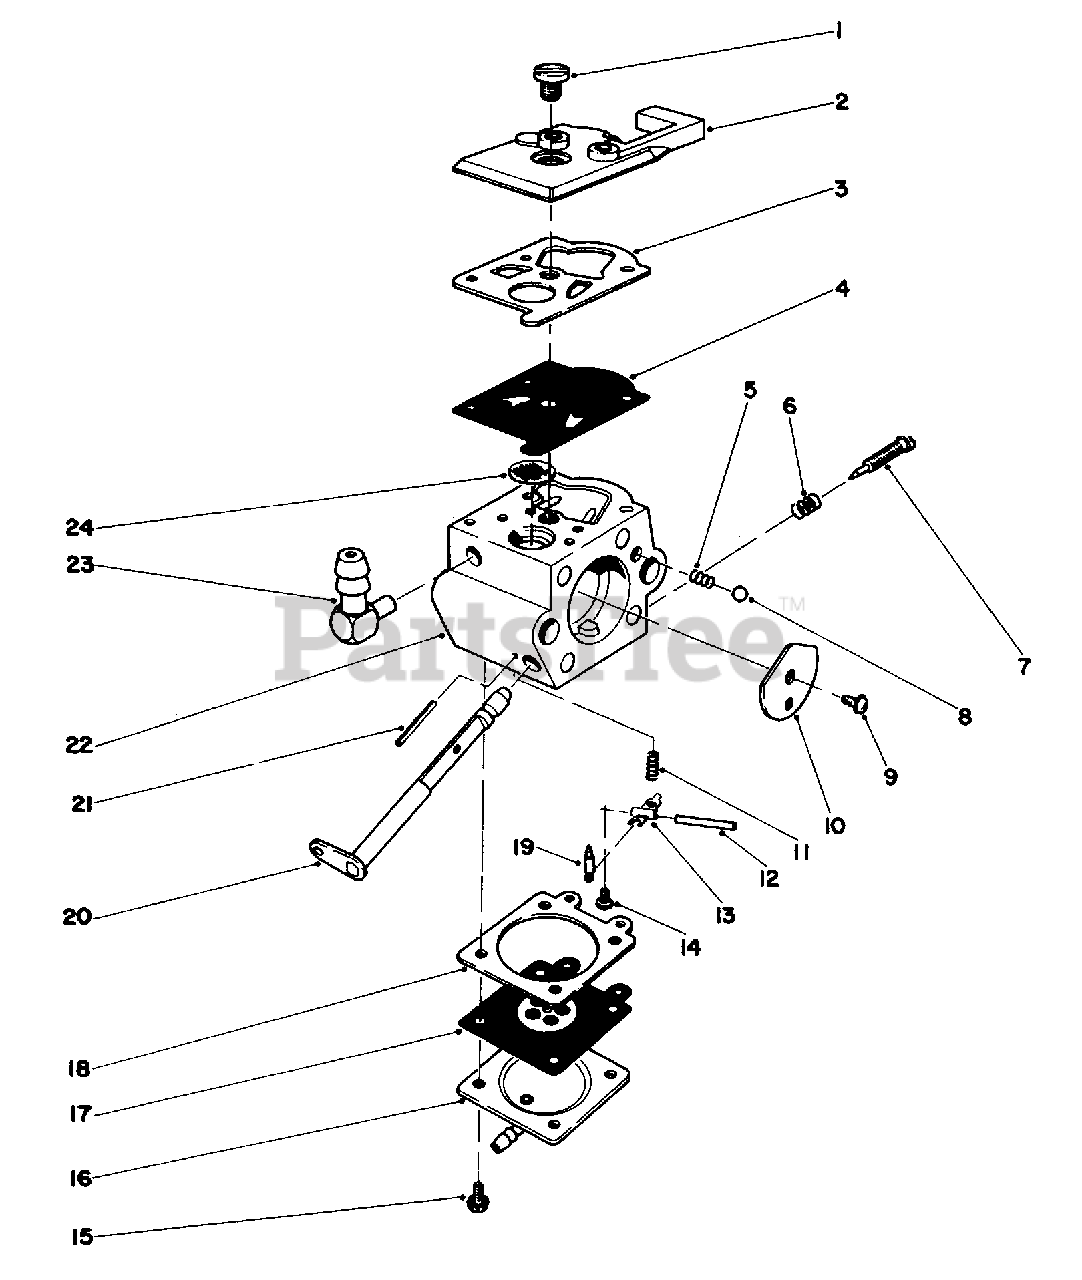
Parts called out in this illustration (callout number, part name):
1	Pump Cover Screw
2	Pump Cover
3	Pump Gasket
4	Pump Diaphragm
5	Choke Friction Spring
6	High Speed Needle Adj. Spring
7	High Speed Needle
8	Choke Friction Ball
9	Valve Screw
10	Choke Valve
11	Metering Lever Spring
12	Metering Lever Pin
13	Metering Lever
14	Metering Lever Pin Screw
15	Metering Diaphragm Screw
16	Metering Diaphragm Cover
17	Metering Diaphragm Assy.
18	Metering Diaphragm Gasket
19	Inlet Needle Valve
20	Choke Shaft Assembly
21	Roll Pin
22	Carburetor Body (Incl. Ref. #21)
23	Fuel Fitting
24	Inlet Screen
